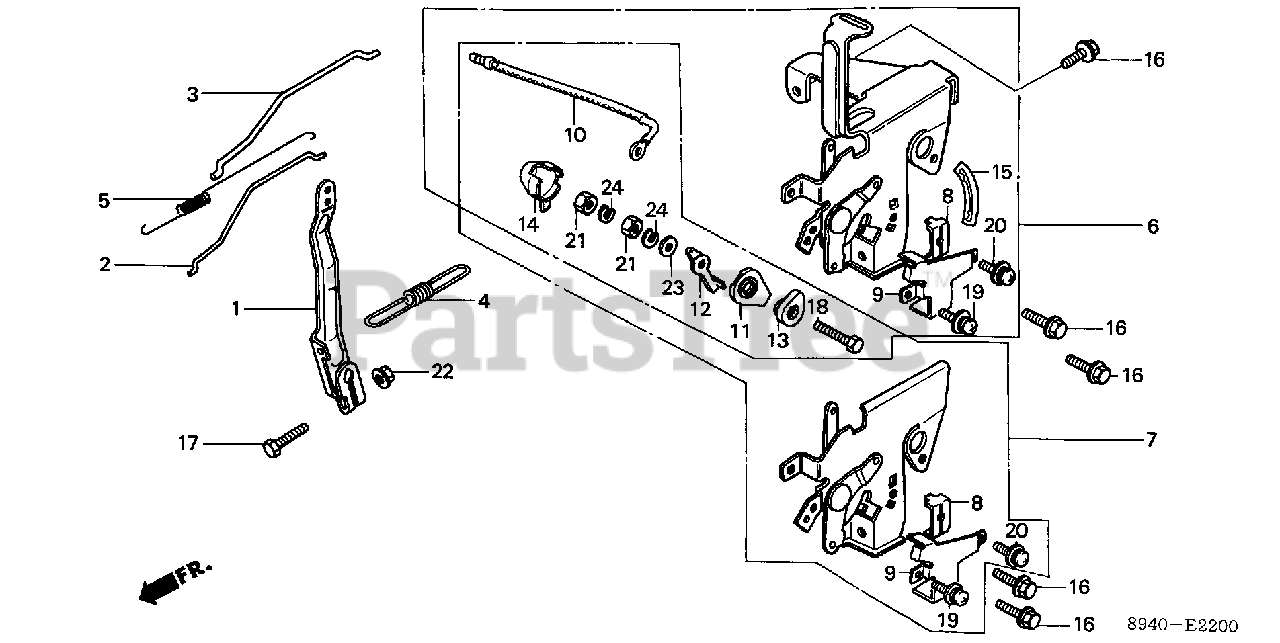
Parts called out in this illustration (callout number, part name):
1	ARM, GOVERNOR
2	ROD, GOVERNOR
3	ROD, CHOKE
4	SPRING, GOVERNOR (NOT AVAILABLE)
5	SPRING, THROTTLE RETURN (NOT AVAILABLE)
6	CONTROL ASSY.
8	HOLDER, CABLE
9	PROTECTOR, CONTROL
10	WIRE, STOP SWITCH
11	BASE, SWITCH
12	CONTACT, SWITCH
13	WASHER, INSULATOR
14	CAP, STOP SWITCH
16	BOLT, FLANGE (6X12) (CT200)
17	BOLT, GOVERNOR ARM
17	BOLT, HEX. (6X20)
18	BOLT, HEX. (4X20)
19	SCREW-WASHER (5X12)
20	SCREW-WASHER (5X20)
21	NUT, HEX. (4MM)
22	NUT, FLANGE (6MM)
23	WASHER, PLAIN (4MM)
24	WASHER, SPRING (4MM)
